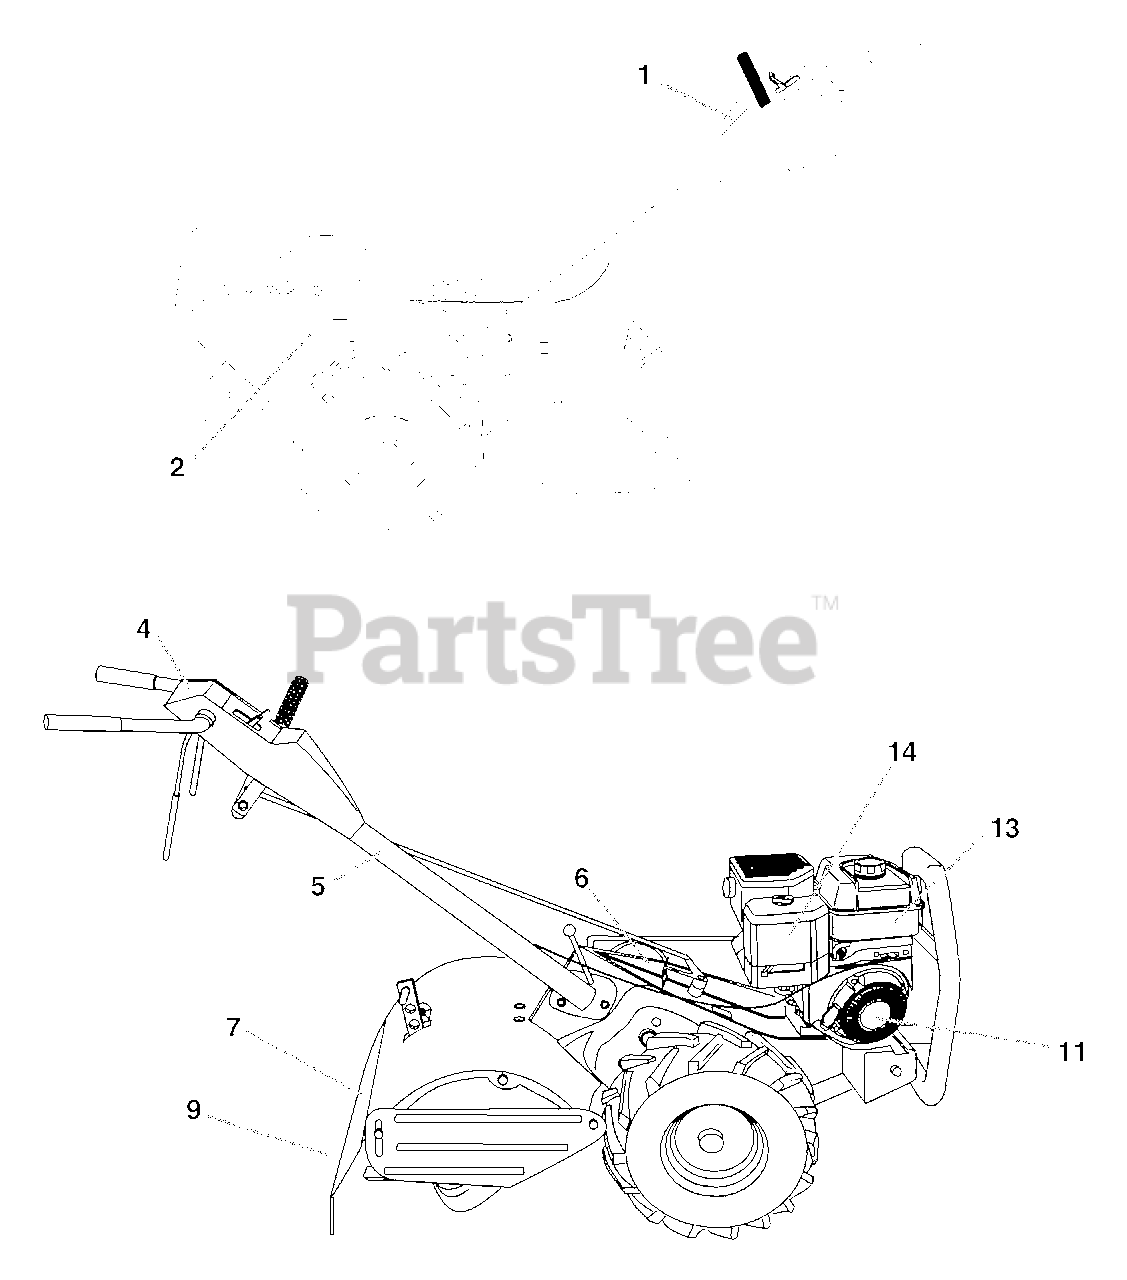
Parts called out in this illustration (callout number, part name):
1	Decal, CNTRL PNL
2	Decal, Decal, Blt Grd
4	Decal, Instruction, Tilling
5	Decal, Hand Placement
6	Decal, Shift Indicator
7	Decal, caution
9	Decal, Warning, Rotating Tines
11	Decal, Rewind
13	Decal, B&S Tank
14	Decal, B&S Air Cleaner
